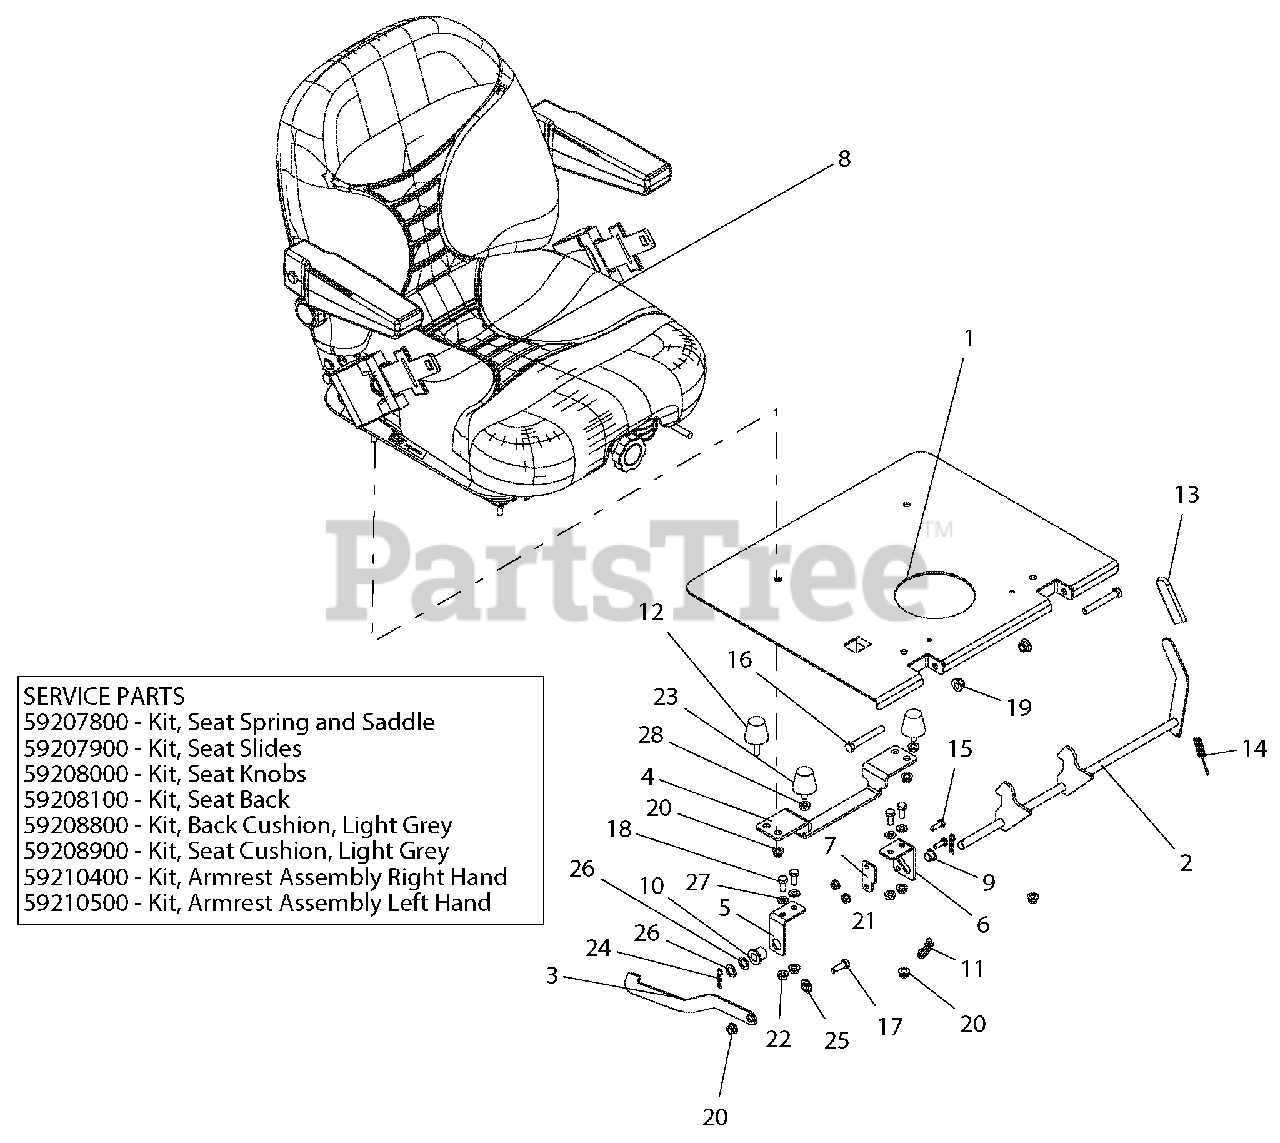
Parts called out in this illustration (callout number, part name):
1	SEAT, PLATE WLDMT W/SAFETY DECALS
2	WMT, SEAT LATCH
3	STOP, SEAT
4	BRKT, SEAT LATCH-BLACK
5	MOUNT, SEAT LATCH - RH
6	MOUNT, SEAT LATCH - LH
7	RETAINER-SEAT LATCH
8	SEAT, SUSPENSION W/SEAT BELT, LT GRAY
9	BUSHING, POLYLINER - .50 SPLIT
10	BSHG, FLANGE .515 X .750 X .745 X 1.00 NYLON
11	CABLE TIE W/ TREE (.25 HOLE)
12	BUMPER, STUD MOUNTED CONE SHAPED
13	GRIP-VINYL-YELLOW .125 x 1.0 x 3.0
14	SPRG, EXTENSION
15	BLT-HEX .25-20X.75 GR5 YWZC
16	BLT-HEX .38-16X2.75 GR5 YWZC
17	BLT-HEX .31-18X1.00 GR5 YWZC
18	BLT-HEX .31-18X.75 GR5 YWZC
19	NUT-LK-NYL-FLG .38-16 YWZC
20	NUT-LK-NYL-FLG .31-18 YWZC
21	NUT, LK-TOP-FLG .25-20 YWZC
22	NUT, LK-TOP-FLG .312-18 YWZC
23	BUMPER, RUBBER CONE STUD MOUNT
24	PIN-HAIR INT .08X.38X1.42 YWZC
25	BSHG, FLG .325X.499X.26X.88
26	WSHR-FL-STL .520X.827X.062 YWZC
27	WSHR-FL-STL.344X.688X.065YWZC
28	@NUT-SPNLK-FLG .312-18 YWZC
